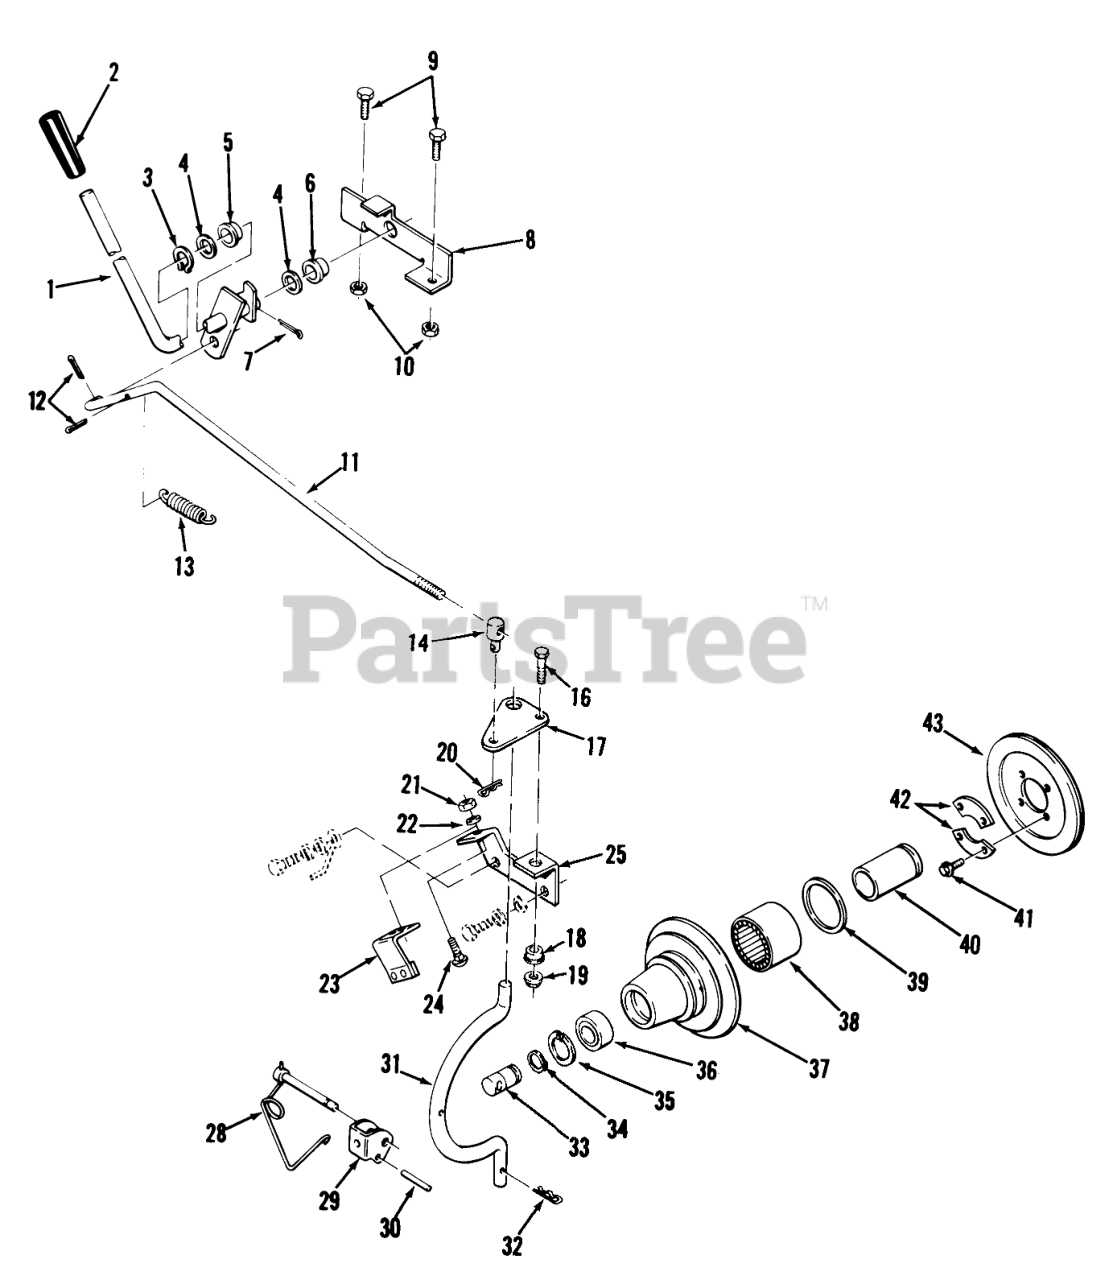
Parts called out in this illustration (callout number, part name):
1	PTO Clutch Lever
2	GRIP
3	Grip Ring
4	SHIM-WASHER
5	BUSHING-NYLINER
6	NYLINER BUSHING
7	Pop Rivet
8	SUPPORT-PTO CLUTCH
9	Bolt
10	Nut
11	PT0 Clutch Rod
12	Pop Rivet
13	SPRING
14	TRUNNION
16	BOLT
17	PTO Plate
18	SPACER-LIFT LINK
19	Nut
20	Hairpin Cotter
21	Nut
23	PTO Brake Assy
24	Bolt-Carriage
25	BRACKET-ENGINE B
28	Pin
29	Clevis
30	PIN-SPIROL
31	ROD-HOUSING
32	Hairpin
33	SHAFT-PTO
34	RING-SNAP, EXTERNAL
35	Ring-Snap
36	BaIl Bearing
37	Housing-Clutch
38	BRG-NEEDLE OPEN END
39	SEAL-OIL
40	BEARING RACE
41	Screw
42	RETAINER
43	Clutch Plate & Facing
